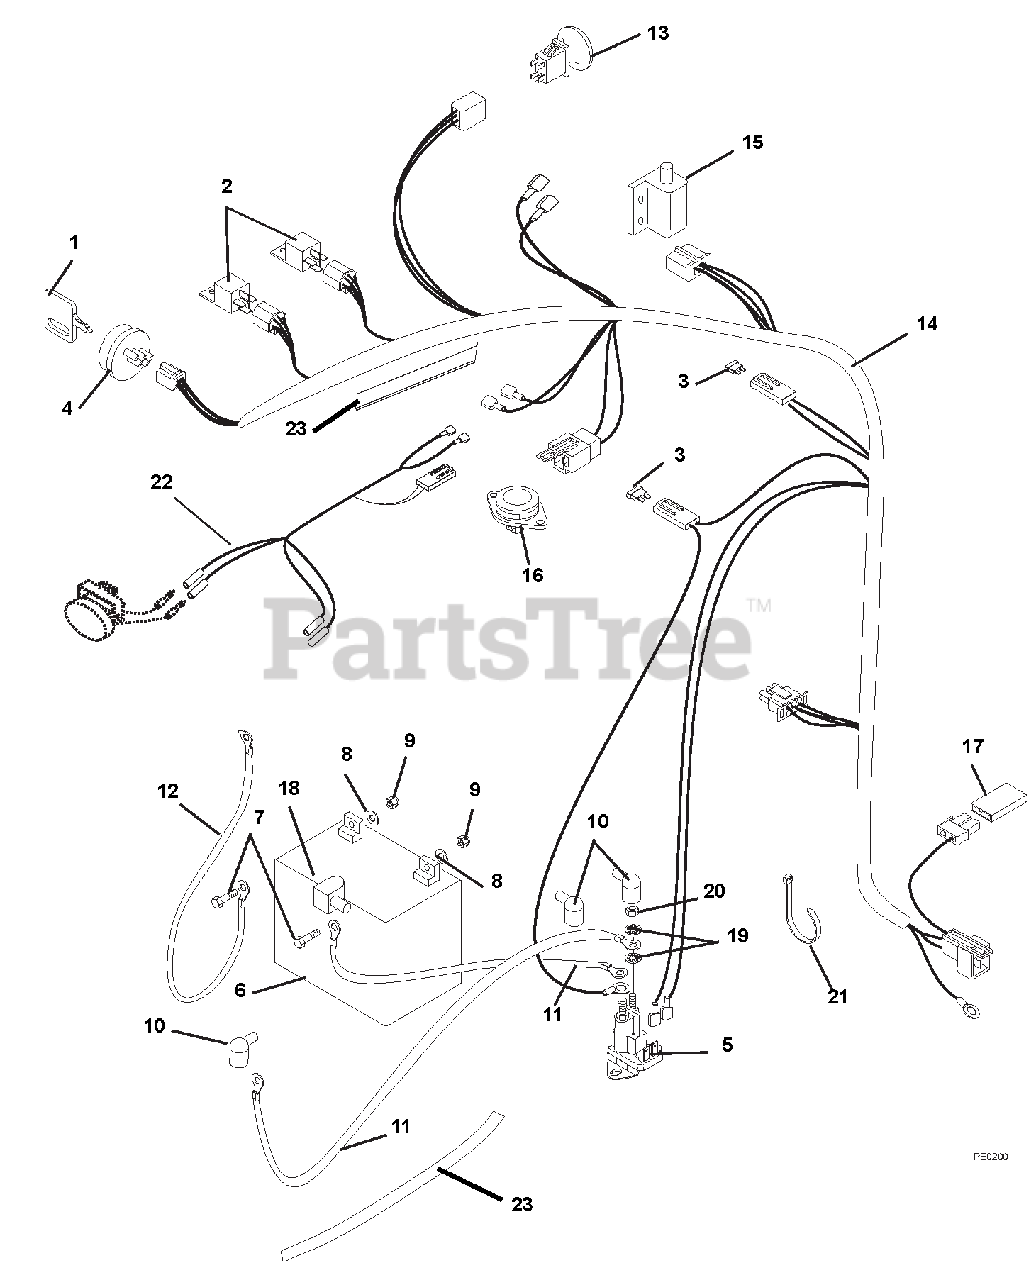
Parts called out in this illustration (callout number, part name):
1	KEY -W/CAP
2	RELAY
3	FUSE-25 AMP ATC TYPE
4	KEY SWITCH
5	SOLENOID, HP RTV
6	Battery, Exide Sealed Maintenance Free U1-250 (Purchase replacement locally)
7	@BLT-HEX .25-20X.75 GR5 YWZC
8	@WSHR-FL-STL.281X.62X.065 YWZC
9	NUT-KEPS .250-20
10	BOOT, EYELET TERMINAL
11	STARTER CABLE 13"
12	GROUND CABLE .31X22.00X.31
13	SWITCH, CLUTCH
14	WIRE HARNESS
15	SWITCH- DOUBLE POLE N.O./N.O.
16	SWITCH- SNAP MTG N.O.
17	DIODE, CONNECTOR SHELL
18	INSULATOR
19	WSHR-LOCK INT .31 YWZC
20	NUT-JAM .31-24 YWZC
21	CABLE TIE LG 5-1/2
22	HARNESS,MINI-Z HEADLIGHT
23	SLEEVE, ANTI-ABRASION
